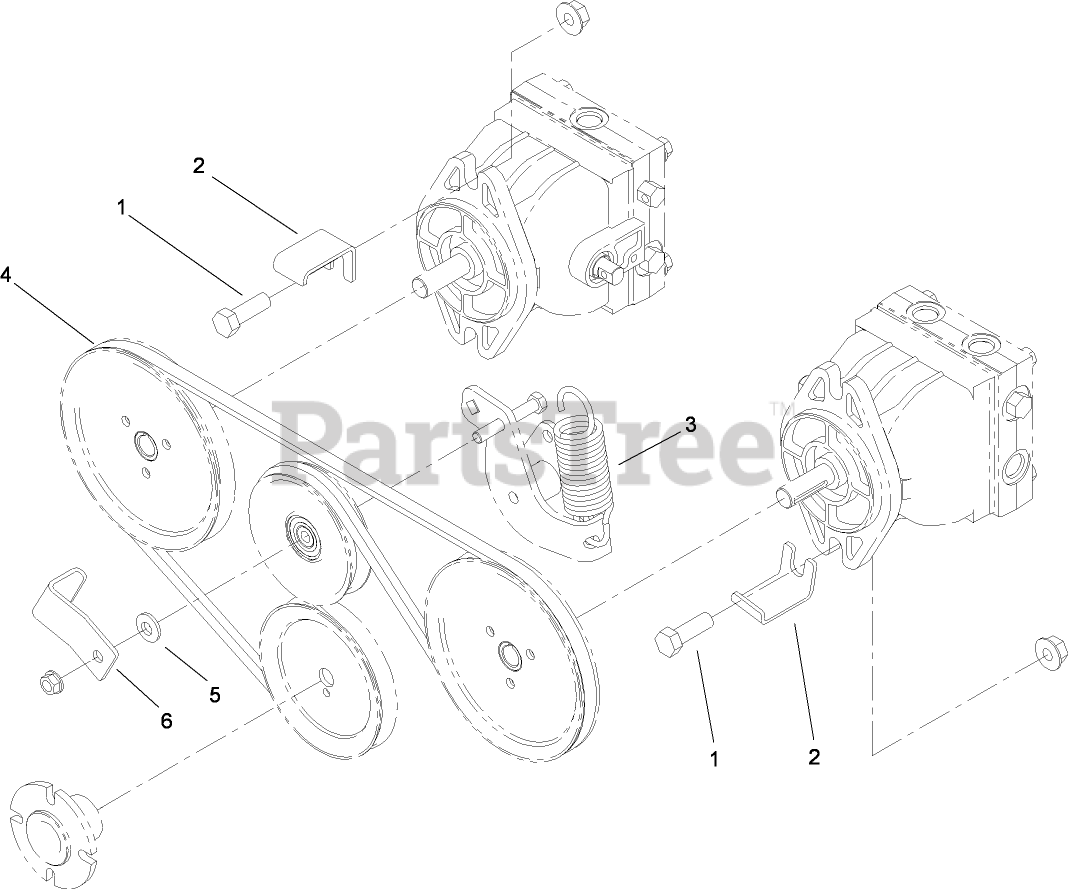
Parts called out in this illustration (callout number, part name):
1	SCREW-HH
2	BRACKET-GUIDE, UPPER BELT
3	SPRING-EXTENSION
4	BELT-V
5	WASHER-BELLEVILLE
6	BRACKET-GUIDE, BELT
